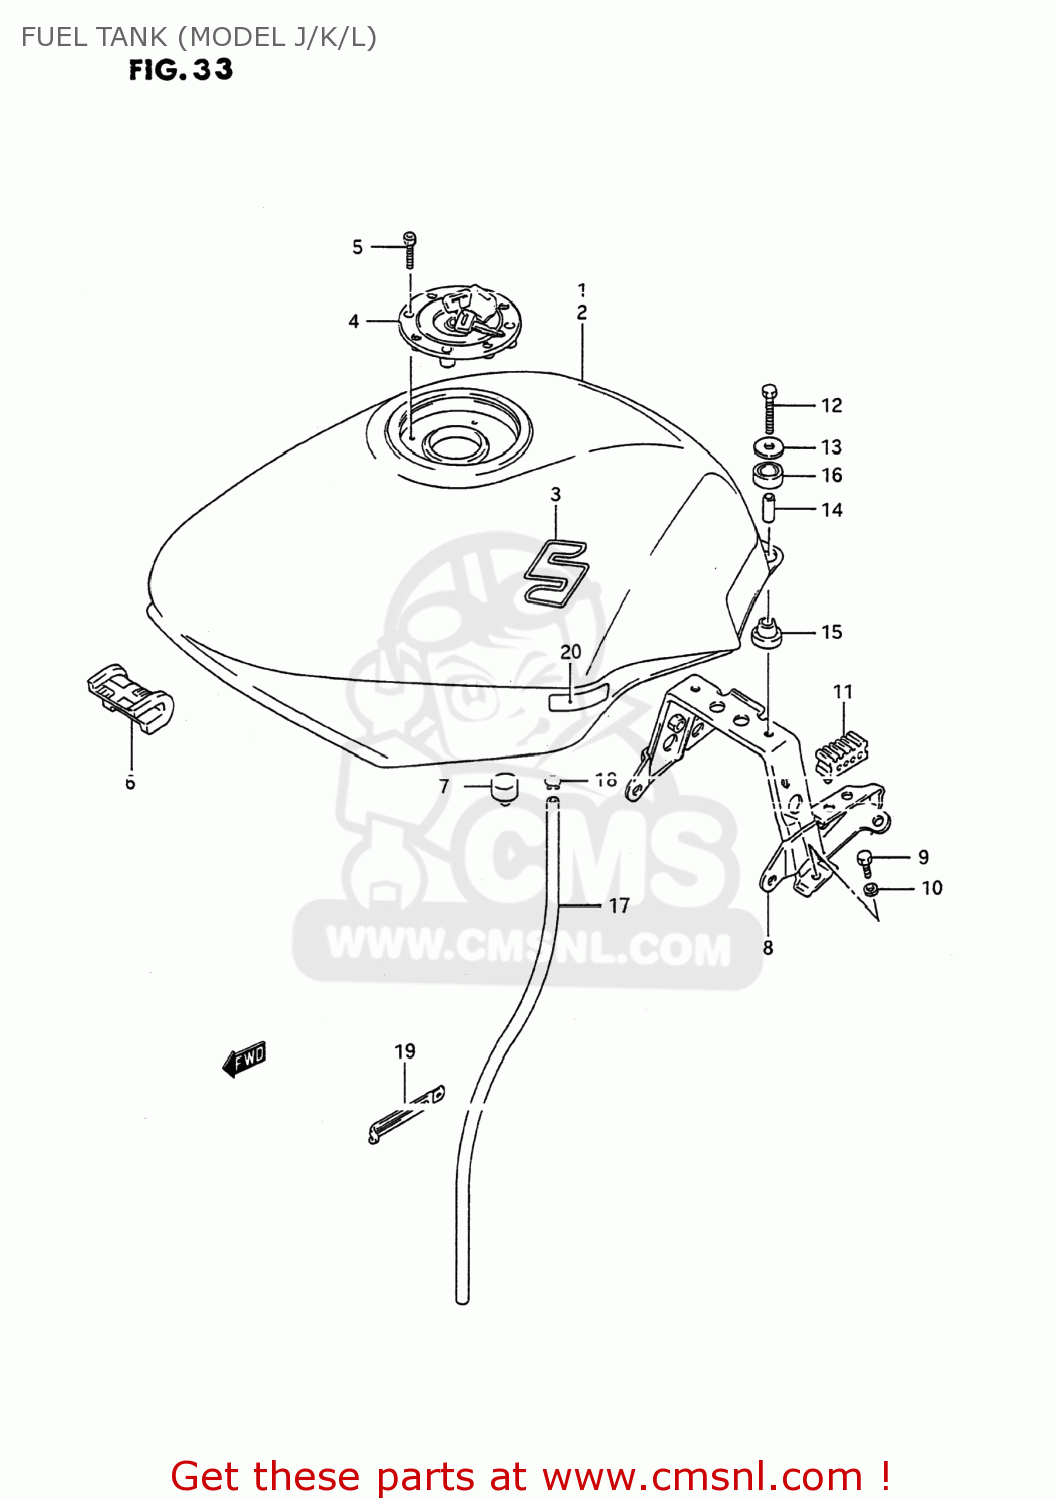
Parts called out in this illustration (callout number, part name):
1	TANK ASSEMBLY,FUEL
2	TANK ASSEMBLY,FUEL
3	EMBLEM
4	CAP SET,FUEL TANK
5	BOLT(5X20)
6	CUSHION,FUEL TANK FR
7	CUSHION
8	BRACKET,FUEL TANK RR
9	SCREW
10	LOCK WASHER
11	CUSHION,SEAT(40X20X15)
12	BOLT
13	WASHER (6.5X24X1.6)
14	SPACER
15	CUSHION
16	CUSHION
17	HOSE,FUEL TANK WATER DRAIN
18	CLIP
19	CLAMP(L:120 T:1.0)
20	PROTECTOR,FUEL TANK,LEFT
